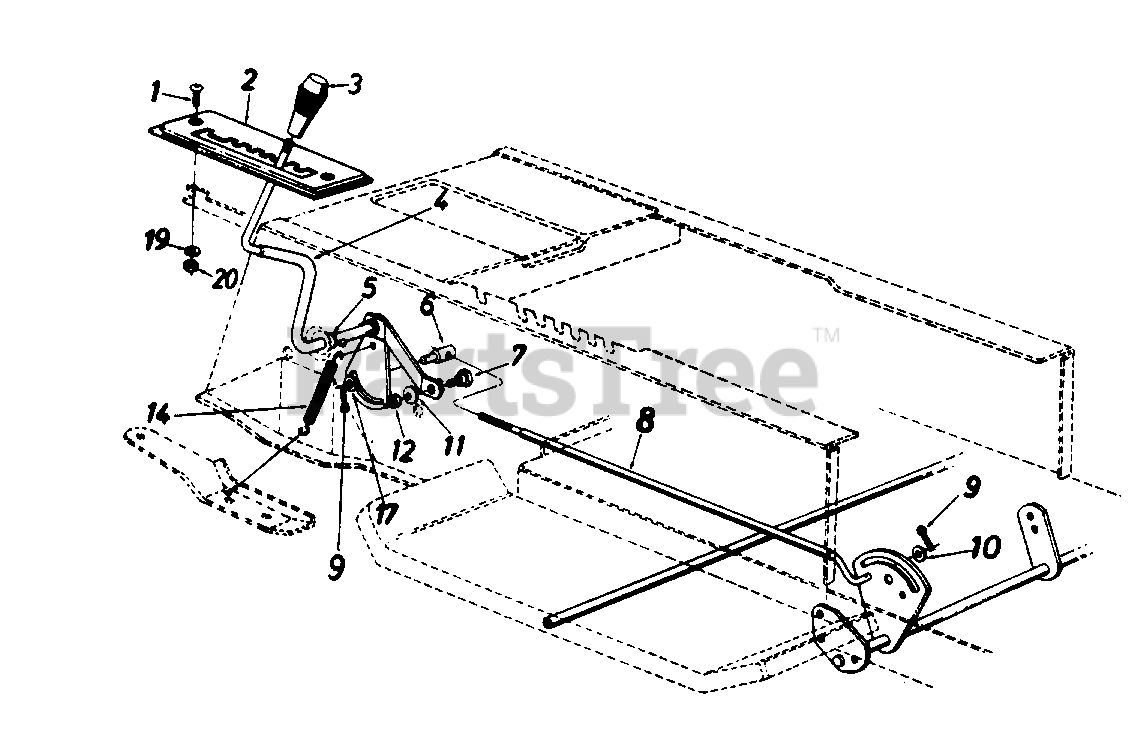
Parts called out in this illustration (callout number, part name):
1	Truss Mach. Scr. 1/4-20 x .75" Lg.
4	Speed Selector Lever Ass'y.
5	Flat Washer .53" I.D. x .93"
6	Ferrule 3/8-24 x .37" Dia.
7	Shoulder Bolt
8	Speed Control Link
9	Cotter Pin 3/32" Dia. x 1.0"
10	Fl-Wash. .469" I.D. x .88"
11	L-Wash. 5/16" I.D.
12	Hex Nut 5/16-18 Thd.
14	Spring .38" O.D. x 3.18" Lg.
17	Fl-Wash. .385" I.D. x .62"
19	L-Wash. 1/4" I.D.
20	Hex Nut 1/4-20 Thd.
